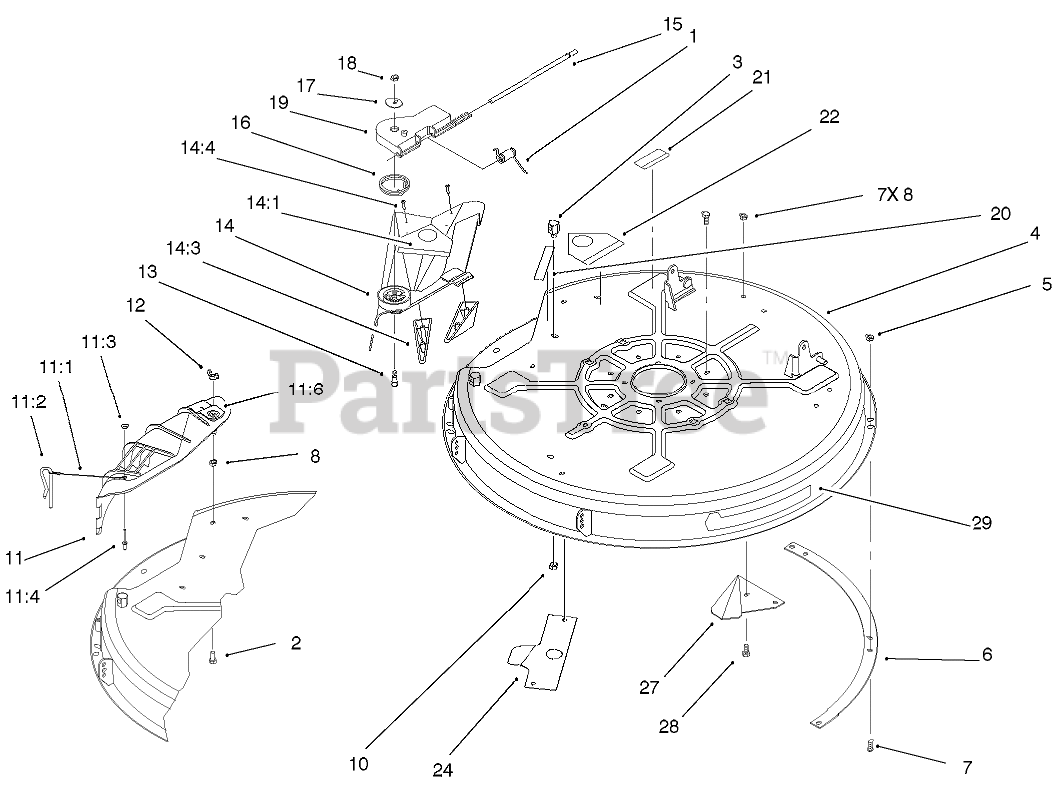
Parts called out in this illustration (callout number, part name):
1	SPRING-TORSION
2	SCREW-HH
3	POST-PIVOT
4	DECK ASM
5	NUT-LOCK, NI
6	RING-DECK
7	SCREW-HH
8	NUT-LOCK, NI
10	NUT-LOCK, NI
11	DISCHARGE COVER ASM
11:1	LANYARD
11:2	PIN-LOCKING, CHUTE
11:3	WASHER-PLAIN
11:4	RIVET-BLIND
12	NUT-WING
13	BOLT-SHOULDER
14	32 INCH DEFLECTOR ASM
14:1	DECAL-DANGER
14:3	KICKER
14:4	SCREW-PPH
15	ROD-HINGE, DEFLECTOR
16	SPRING-TORSION
17	WASHER-FLAT
18	NUT-LOCK, NI
19	PIVOT-HINGE, DEFLECTOR
20	DECAL-DANGER
21	DECAL-WARNING
22	DECAL-DANGER
24	RAMP-DEFLECTOR
28	SCREW-HH
29	DECAL - RECYCLER 32"
